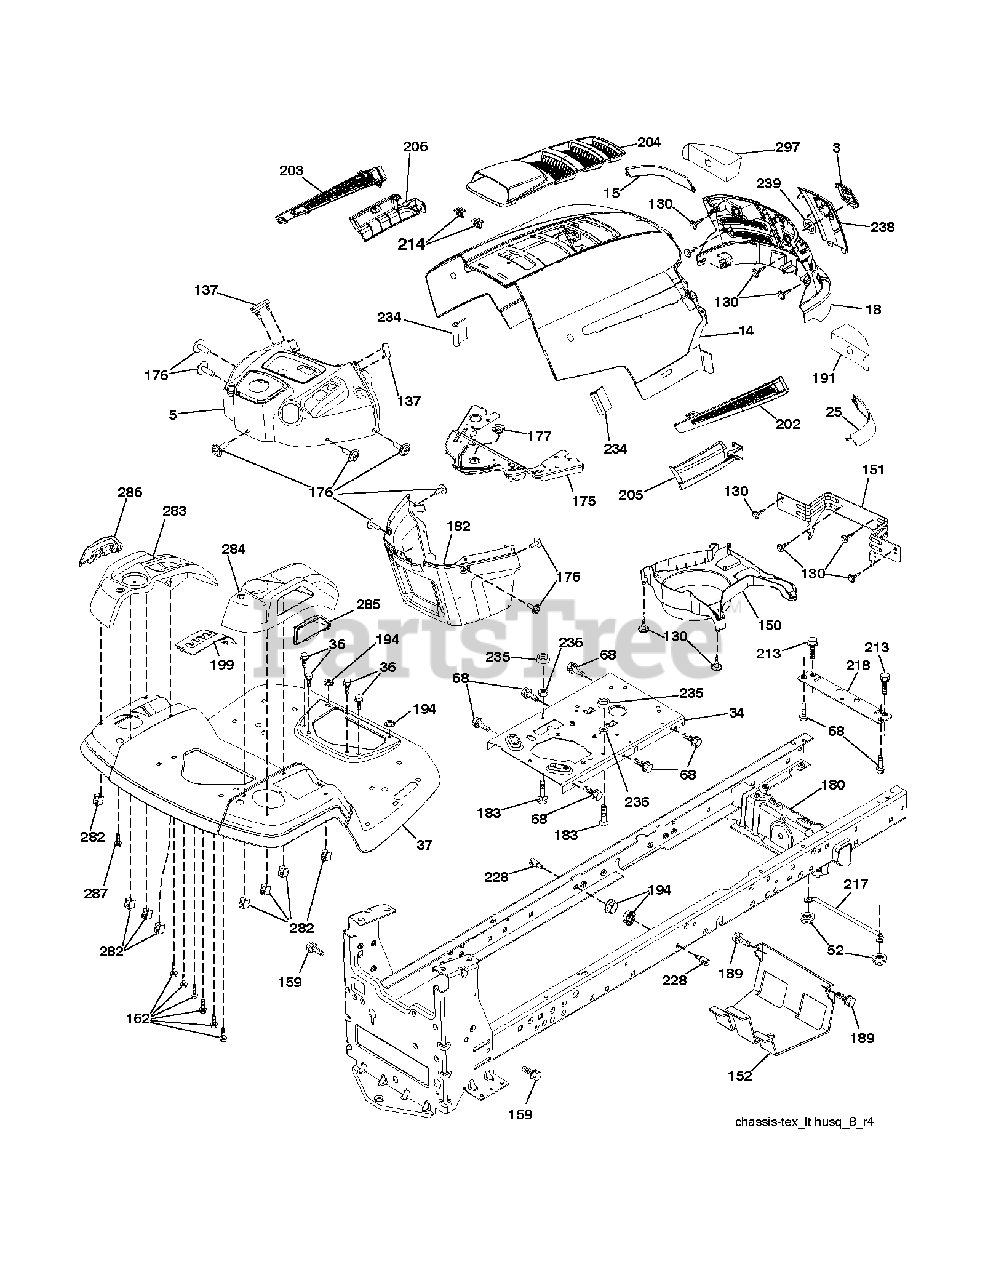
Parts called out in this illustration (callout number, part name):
3	LOGO.HUSQ.GT.LT.CROWN.H
5	SUBASM.DASH.UPPER.HLT.498
14	HOOD
15	LENS.HUSQVARNA LT.RH
18	GRILLE.SVC.HUSQVARNA.GREY
25	LENS.HUSQVARNA LT.RH
34	PLATE PLATE ENGINE
36	SCREW 5/16"
37	FENDER.TLT.FS.W/NO CUPHLD.667
52	LOCKNUT
68	SCREW LT
130	SCREW.#10 X 0.750.BOS
137	BUMPER DASH
151	BRACKET PIVOT
152	SHIELD.BROWNING.W/TEX
159	SCREW, 3/8-16X3/4
162	SCREW.HI-LO.CONSOLE
175	CROSSMEMBER
176	SCREW.#10-24X5/8.RN.QU
177	BUSHING STEERING
180	CHASSIS
182	DASH.LOWER.PREDATOR LT
183	BOLT.5/16-18X1-1/4 FULL THD
189	SCREW
191	INSERT.REFLECTIVE.RH.
194	NUT LOCK HEX FLANGE 5/16-18
199	PLATE.DECK.LIFT.HUSQ.LT
202	VENT.SIDE.HUSQVARNA.LT.RT
203	VENT.SIDE.HUSQVARNA.LT.LFT
204	SUBASM.TOP.VENT.HUSQ.LT
205	SKIRT.SIDE.HUSQVARNA.LT.RT
206	SKIRT.SIDE.HUSQVARNA.LT.LEFT
213	BOLT
214	CLIP.RETAINER.TINNER.
217	ROD.PIVOT.HOOD
218	X-PIECE.HOOD.STOP.NON/
228	STUD.FASTNER.W/ANTI-ROTATE
234	BUMPER.HOOD.TEX.HUSQVARNA
235	SPACER FENDER
236	NUT.CENTERLOCK.5/16-
238	TRIM.HUSQ LT.668
282	CLIP.RETAINER.CONSOLE.LT.HUSQ
283	CONSOLE.ASM.LFT.RSF.HUSQ.LT
284	CONCOLE.CNTRL.PDL.HUSQ.LT.498
285	CONSOLE INSERT RH
286	CONSOLE.INSRT.LH.HUSQ.LT.BLACK
287	SCREW 1/4X20
297	INSERT REFLECTIVE
